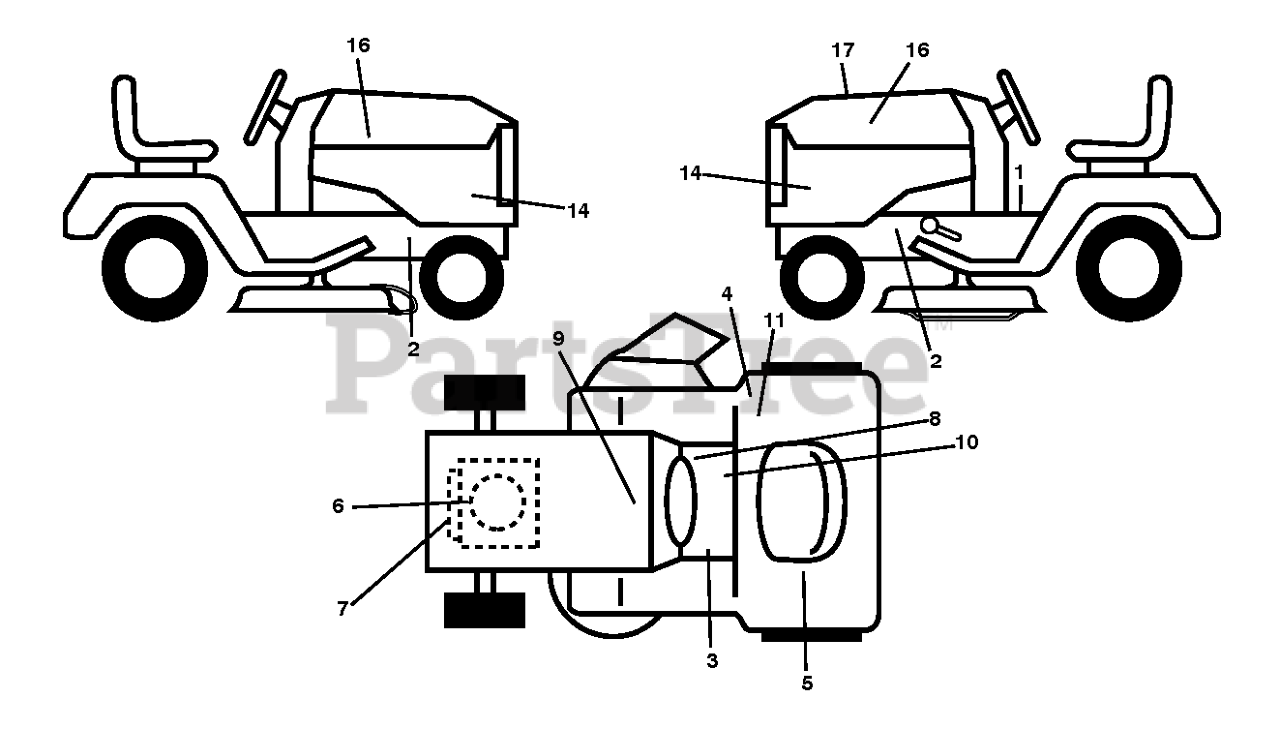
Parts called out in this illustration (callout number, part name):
1	LABEL
3	DECAL
4	DECAL 80 DBA
5	DECAL.WARN.RESERVE.FUEL
6	DECAL.ENGINE.BS27.ENDU.2794718
7	DECAL
8	DECAL PARK BRAKE
9	DECAL BTRY SYMBOLS
10	DECAL
11	DECAL
14	Decal, Panel Side
16	RP.DECAL.BADGE.170MM.TEXTLOGO
17	Decal, Replacement
